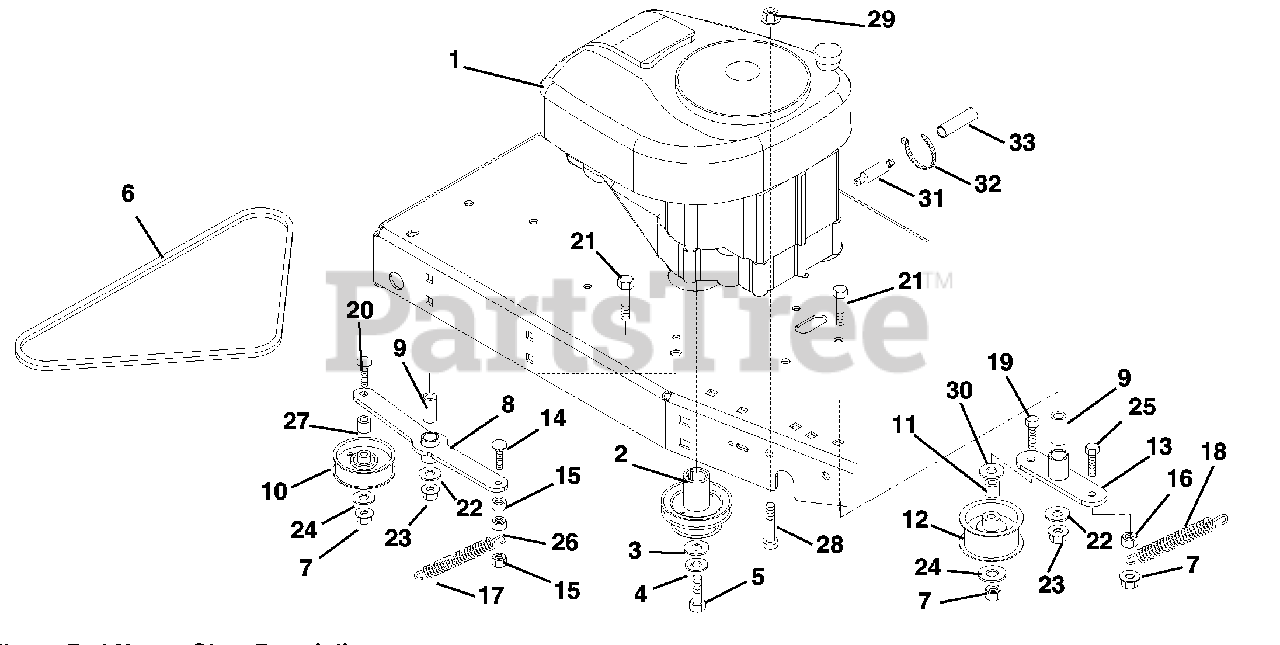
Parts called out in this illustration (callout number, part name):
1	ENGINE GROUP-12 HP
2	ENGINE-SHEAVE
3	WSHR-FL-STL.511X1.441X.125 YWZ
4	@WSHR-LK .44X.109 REG YWZC
5	BLT-HEX .44-20X1.50 GR5 YWZC
6	V-BELT, HA-RAW EDGE
7	NUT-LK-TOP-FLG .38-16 BLKZC
8	WLDM'T-IDLER (IZT)
9	BSHG-SLV .500X.750X1.560
10	IDLER-PLY FLAT 3.25 X .38 X1.0
11	BSHG-SPCR .41X75X.69
12	IDLER 2.75X1.25
13	BRKT, IDLER (WLDMNT)
14	@BLT-RDHDSQNK .31-18X1.25 G5YZ
15	NUT-LK ESNA THIN .50-13 YWZC
16	@NUT-SPNLK-FLG .375-16 YWZC
17	SG-TENS .075X.75X2.25 WLD20.7
18	SG-TENS .080X.687X5.16 WLD 28
19	@BLT-HEX .38-16X2.75 GR5 YWZC
20	@BLT-RDHDSQNK .38-16X2.00 G5YZ
21	@BLT-HEX .50-13X2.25 GR5 YWZC
22	@WSHR-FL-STL.563X1.38X.109YWZC
23	@NUT-LK-TOP-FLG .50-13 YWZC
24	@WSHR-FL-STL.438X1.00X.083 YWZ
25	@BLT-HEX .38-16X1.25 GR5 YWZC
26	@NUT-SPNLK-FLG .312-18 YWZC
27	BSHG-SLV .391X.688X.52 PM
28	SCR-SKH BTHD .31-18 X 1.50 GR8
29	@NUT-LK-TOP-FLG .31-18 YWZC
30	WSHR,FLT .438X1.00X.160 ZCC
31	VALVE, OIL DRAIN
32	CABLE TIE LG 5-1/2
33	TUBE, OIL DRAIN 8" CLEAR VINYL
